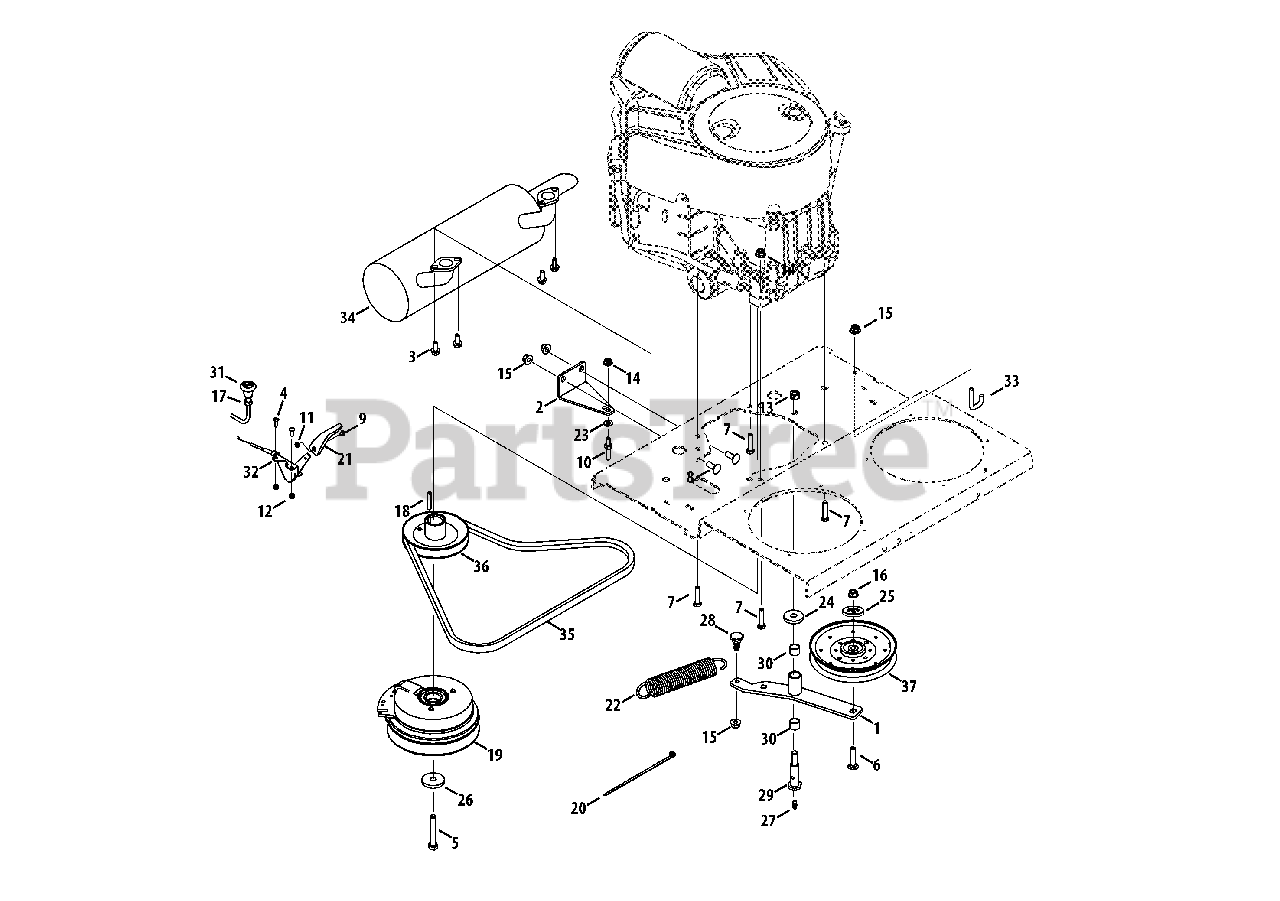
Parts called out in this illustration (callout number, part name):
1	Idler Bracket
2	Clutch Retainer Bracket
3	Hex Flange Screw, 5/16-18
4	Screw, #10-24 x .625
5	Hex Cap Screw, 7/16-20 x 2.75
6	Carriage Bolt, 3/8-16 x 1.00
7	Hex Cap Scrw, 5/16-18 x 1.50
8	Carriage Bolt, 3/8-16 x 1.00
9	Screw, #8-32 x .375
10	Stud, Pivot Ball Joint
11	Nut, #8-32, Hex
12	Nut, #10-24, Hexlock
13	Nut, 7/16-14, Hexlock
14	Nut, 5/16-18, Flangelock
15	Nut, 3/8-16, Flangelock
16	Nut, 3/8-16, Flangelock
17	Jam Nut, 3/8-24
18	Key, 1/4 x 1.50
19	Electric PTO Clutch
20	Cable Tie
21	Throttle Control Knob
22	Extension Spring, 1.5 x 7.5
23	Washer, .344 x .688 x .065
24	Washer, .471 x 1.50 x .225
25	Pulley Cap
26	Washer, .471 x 1.50 x .225
27	Grease Fitting
28	Shoulder Screw, .625 x .302, 3/8-16
29	Shoulder Bolt, .625 x 1.947, 7/16-14
30	bearing, .638 x .753 x .615
31	Choke Control Cable
32	Throttle Cable
33	Transmission Spring Hook
36	Drive Pulley
37	Idler Pulley
